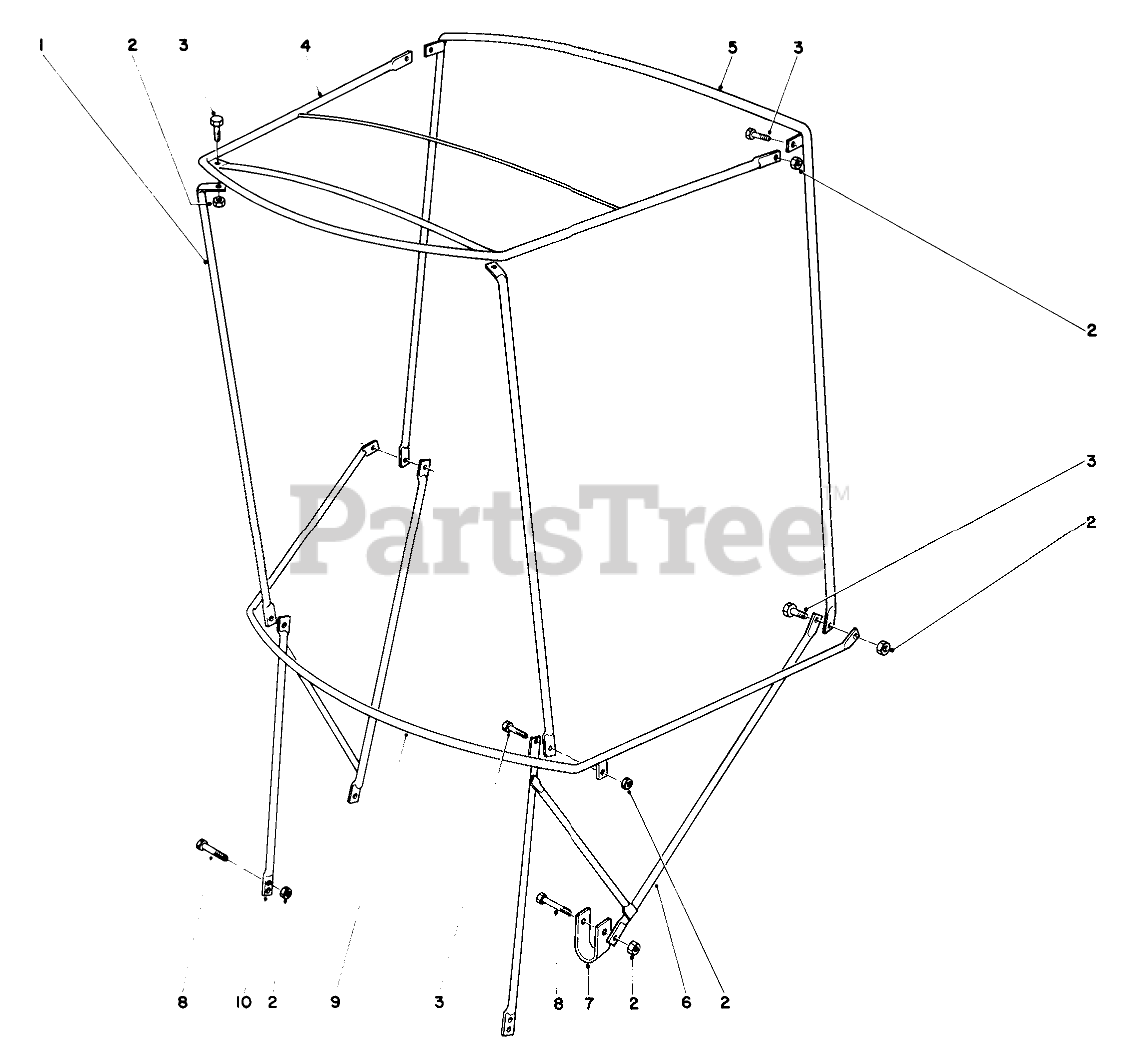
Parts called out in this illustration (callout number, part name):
2	NUT-HEX, SIDE DEFORM
3	Bolt
4	FRAME-TOP
5	BOW-VERTICAL, REAR
6	ATTACHING BRKT L
7	U CLAMP
8	SCREW-HH
9	BOW-CURVED
10	Attaching Bracket R.H.
